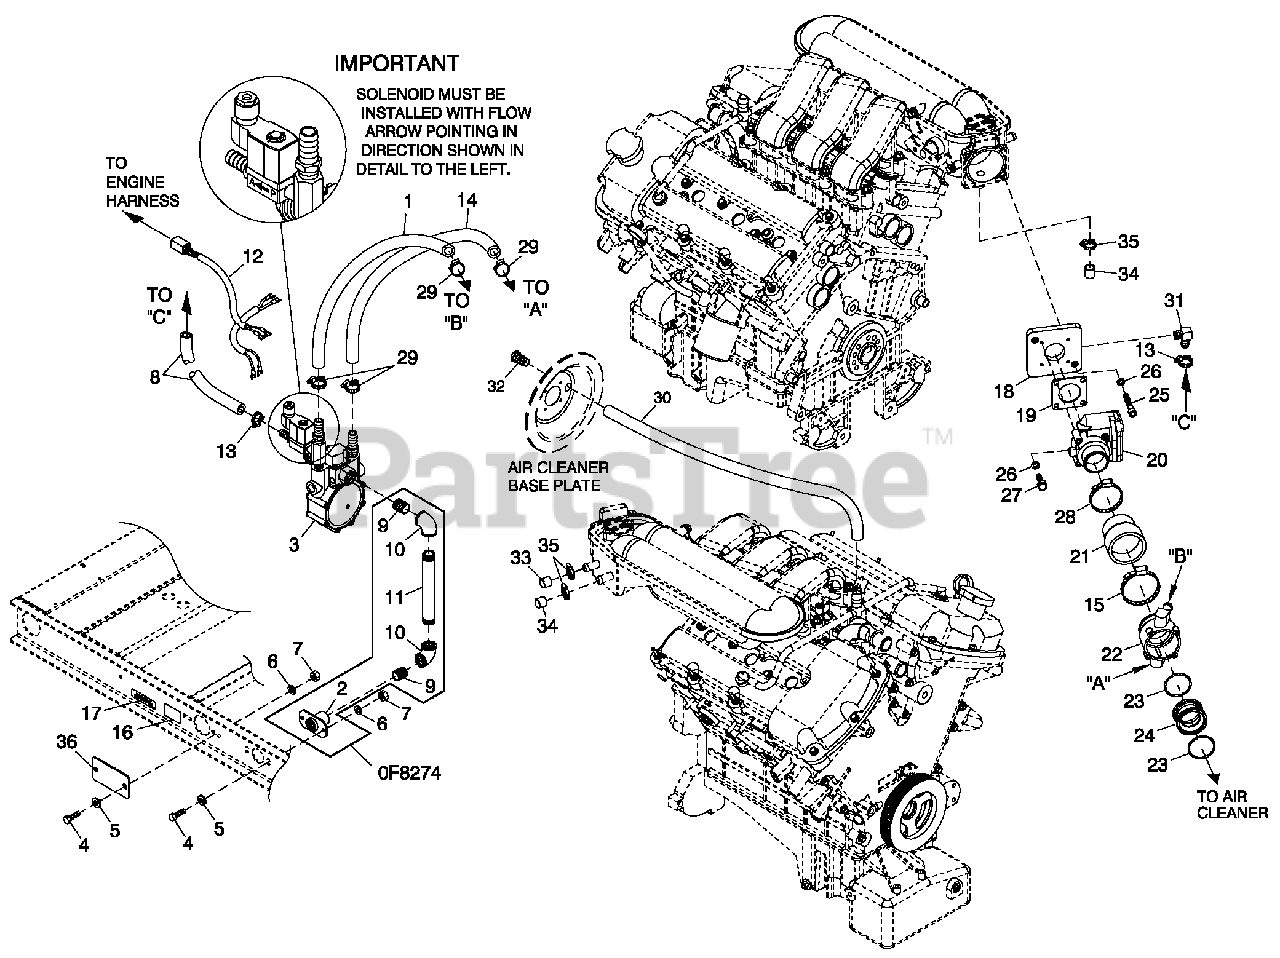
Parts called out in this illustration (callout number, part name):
1	HOSE 3/4 ID SAE-30R2 (28" LG)
2	FLANGE FUEL INLET
3	ASSYREGULATR60KWLP
4	SCREW HHC $8-1.25X20 G8.8
5	WASHER FLAT 5/16-M8 ZINC
6	WASHERLOCK M8-5/16
7	NUT HEX M8-1.25 G8 CLEAR ZINC
8	HOSE 3/8 ID SINGLE BRAID (17" LG)
9	NIPPLE CLOSE 3/4X1.375
10	ELBOW 90D 3/4 NPT
11	NIPPLE PIPE 3/4 NPT X 7
12	HARNESS FUEL JUMPER SINGLE REG
13	CLAMP HOSE #8 .53-1.00
14	HOSE 3/4 ID SAE-30R2 (22" LG)
15	CLAMP HOSE #44 2.31-3.25
16	DECAL INLET PRESSURE
17	DECAL FUEL INLET LPG
18	INTAKE ADAPTER BOSCH
19	GASKET BOSCH 32 & 40
20	ACTUATOR BOSCH 40 GOVERNOR
21	REDUCER RUBBER 3.0"-2.00"
22	MIXER 40/60MM ACTUATOR ASSY
23	O-RING 2-3/4X3/32X2-15/16
24	VENTURI THROTTLE 32MM
25	SCREW SHC M6-1.0 X 25 G12.9 ZP
26	WASHER LOCK M6-1/4
27	SCREW HHC M6-1.0X 50 G8.8
28	CLAMP HOSE #36 1.88-2.75
29	CLAMP HOSE #10 .56-1.06
30	HOSE COOL 5/8" ID 250#WP (24" LG)
31	BARBED EL 901/4 NPT X 3/8
32	ADAPTER INSERT HOSE BARB 5/8"
33	CAP VINYL .5" ID X 1.0" DPBLK
34	CAP VINYL 3/8" ID X1" DPBLK
35	CLAMP HOSE .38-.87
36	COVER FUEL INLET NG
